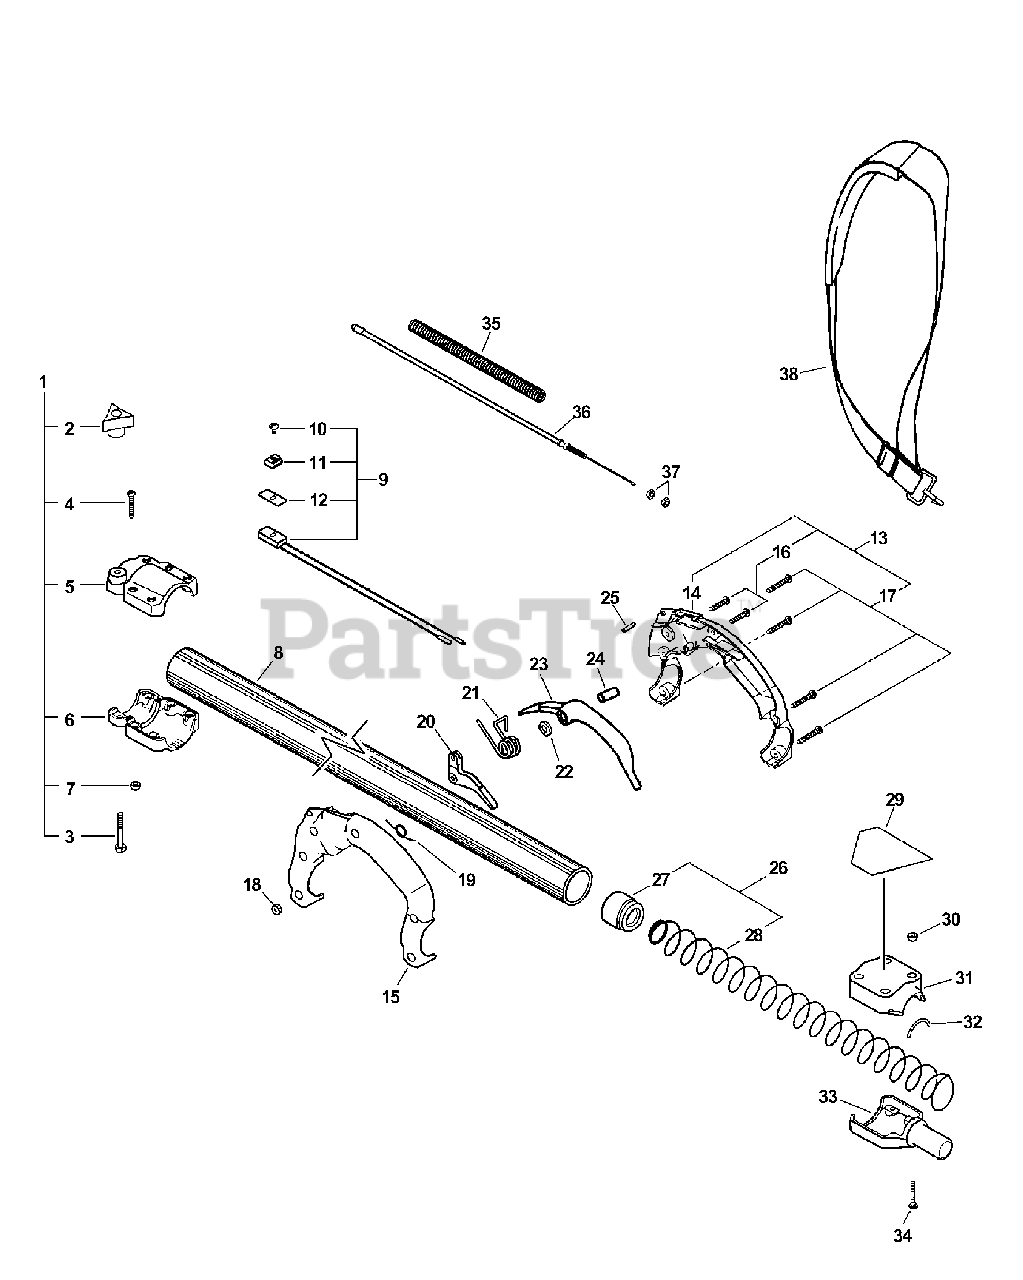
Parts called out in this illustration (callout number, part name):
1	CLAMP ASSY
2	THUMBSCREW
4	SCREW, TORX 10-24 UNC 1-1/4
5	COLLAR, UPPER
6	COLLAR, LOWER
7	NUT, LOCK 10-24 UNC
8	PIPE, MAIN
9	SWITCH, ON-OFF
10	SCREW 3×10
11	KNOB, SWITCH - ORANGE
12	LABEL, SWITCH
13	HANDLE SET, REAR
14	HANDLE, RIGHT REAR
15	HANDLE, LEFT REAR
16	SCREW, TORX 10-24 UNC 1-1/4
17	SCREW, TORX 10-24×1.5
18	NUT, LOCK 10-24 UNC
19	SPRING, TORSION
20	TRIGGER, THROTTLE
21	SPRING, TORSION Ø0.39 I.D.
22	WASHER 5.5×12×0.8
23	LOCKOUT, THROTTLE
24	COLLAR 5.08×14.5
25	PIN, LOCATING 0.17 OD×0.75 L
26	BUSHING ASSY, FLOATING
27	BUSHING, FLOATING
28	SPRING, COMPRESSION
29	LABEL, CAUTION
30	NUT, LOCK 10-24 UNC
31	CAP, MAIN PIPE
33	ADAPTER, LOWER SHAFT TUBE
34	SCREW, TORX 10-24×1.5
35	TUBE, FLEXIBLE
36	CABLE, THROTTLE
38	STRAP ASSY, SHOULDER
